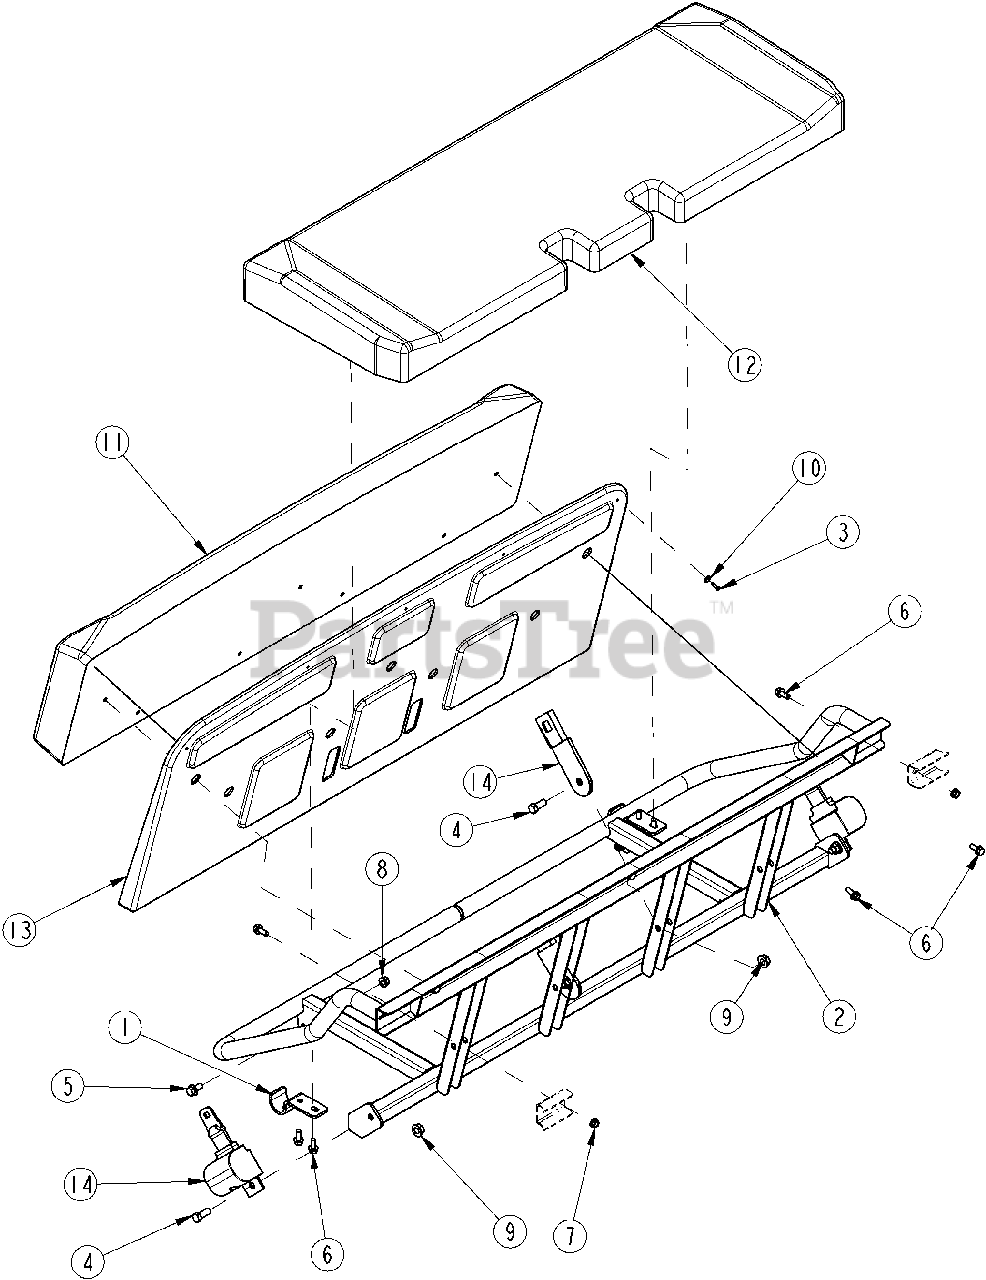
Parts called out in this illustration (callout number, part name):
1	SEAT PIVOT PLATE
2	BENCH SEAT WELDMENT
3	SCREW, OVPH SM 8 X 3/4 SS
4	BOLT, HEX 7/16-14 X 1 GR5
5	HFSS 3/8-16X3/4 LG
6	HFS 5/16-18X3/4 GR5
7	NUT HEX FLG TP LK 5/16-18ZNYCR
8	NUT FLANGE LOCK 3/8-16 PLT
9	NUT HEX FLANGE LOC 7/16-14 PLT
10	WASHER, #8 FINISH CUP
11	BENCH SEAT BACK TAN (ST)
11	BENCH SEAT BACK CUSH, BLACK
12	BENCH SEAT BOTTOM TAN (ST)
12	BENCH SEAT BOTTOM CUSH, BLACK
13	BENCH SEAT BACK PANEL
14	SEAT BELT, RETRACTABLE
